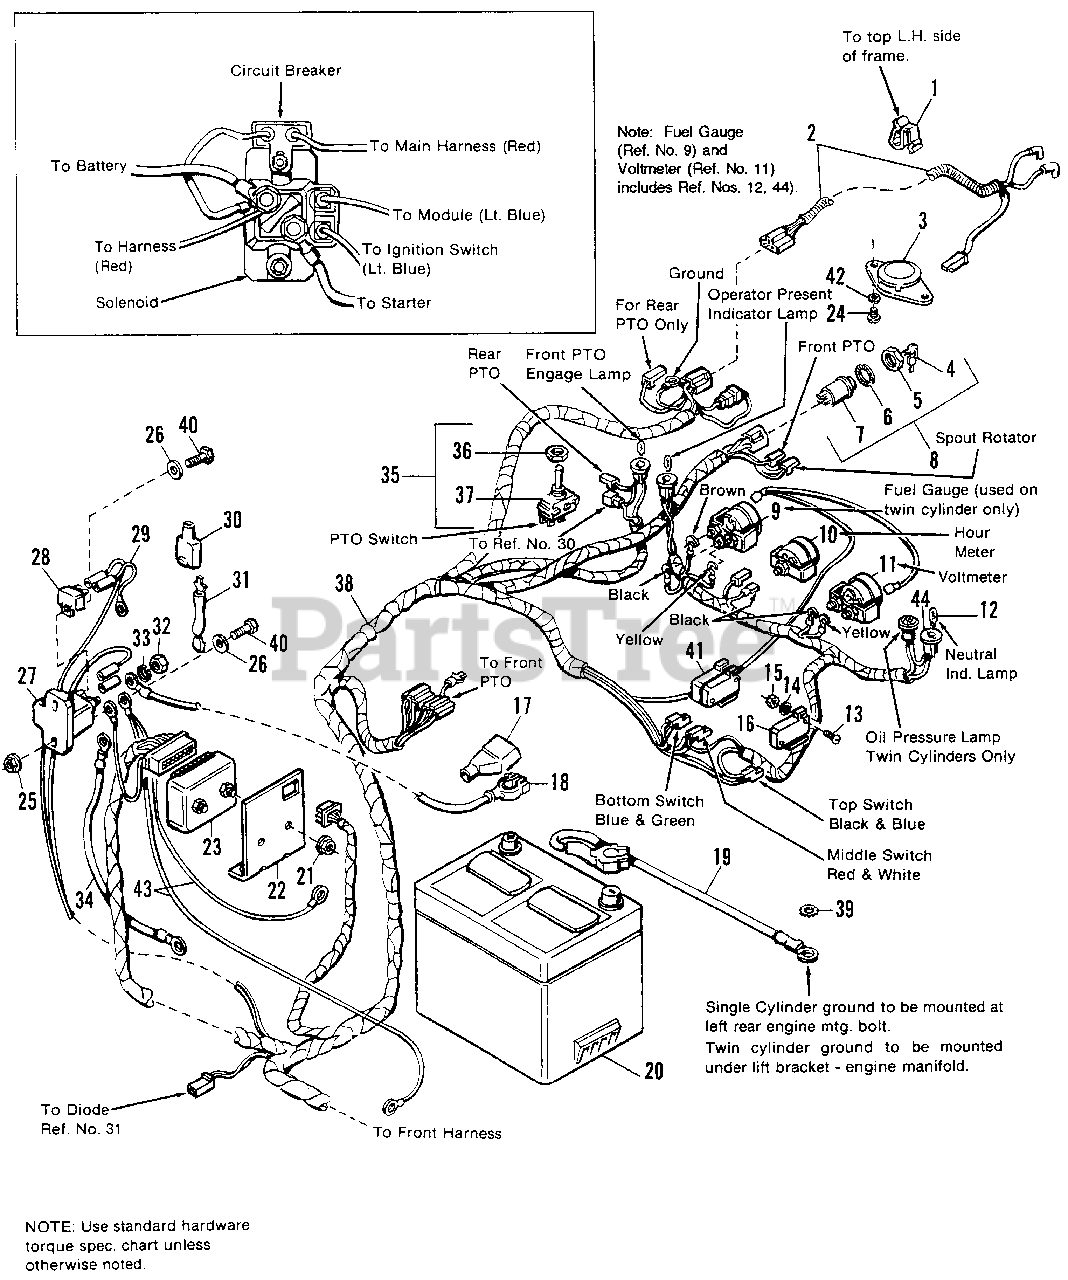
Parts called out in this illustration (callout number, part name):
1	CLIP, Tinnerrnan
2	HARNESS, Rear
3	SAFETY SWITCH (Seat), Operator Present
3	* SAFETY SWITCH (Seat), Operator Present
5	NUT, Special
8	SWITCH 8 KEY ASSY., Ignition (Incl. Ref. Nos. 4 thru 7)
9	GAUGE, Fuel (Twin cylinder Models Only)
12	LAMP (Qty. 3 used on Single Cylinder Models)
13	SCREW, R.H., #5-24 x 1-1/2
14	LOCKWASHER, #5
15	NUT, Hex, #5-40
16	SWITCH, Interlock (Under Dash) Shift Lever
17	PROTECTOR, Battery (Red)
18	CABLE (Battery to Solenoid)
19	CABLE (Battery to Ground)
20	BATTERY (491 AMP Cold Crank Rating)
21	NUT, w/Washer, #8-32
22	BRACKET, Interlock, Mod.
23	INTERLOCK MODULE
24	SCREW, Rnd. Hd., 1/4-20 x 1/2
24	* SCREW, Rnd. Hd., 1/4-20 x 3/4
25	NUT, Hex, Flange, Whizlock 1/4-20
26	WASHER, Plain, 1/4 (Qty. 2 on 1691250, 1691357 only)
27	SOLENOID (12 Volt DC)
28	BREAKER, Circuit
29	WIRE ASSY. (Circuit Breaker to Solenoid)
30	CONNECTOR, 3 Way
31	WIRE ASSY., Diode
32	NUT, Hex, Jam, 5/16-24 Pltd.
33	LOCKWASHER, 5/16, Pltd.
34	CABLE, (Solenoid to Starter)
35	SWITCH ASSY., PTO (incl. Ref. Nos. 36 & 37)
36	NUT, Special
38	WIRING HARNESS (Main)
39	LOCKWASHER, Ext., 3/8 Pltd. (Used on 1691250, 1691357 only)
39	LOCKWASHER, Ext., 5/16 Pltd. (Used on 1691380, 1691381, 1691528, 1691710, 1691924, 1691926, 1691928, 1691953)
40	CAPSCREW, Hex Hd., 1/4-20 x 3/4
41	DUAL INTERLOCK SWITCH
42	LOCKWASHER, Ext. 1/4
43	WIRE ASSY., Harness to Engine Ground (Not used on Mfg. Nos. 1691924, 1691926, 1691928, & 1691953)
44	BULB HOLDER
